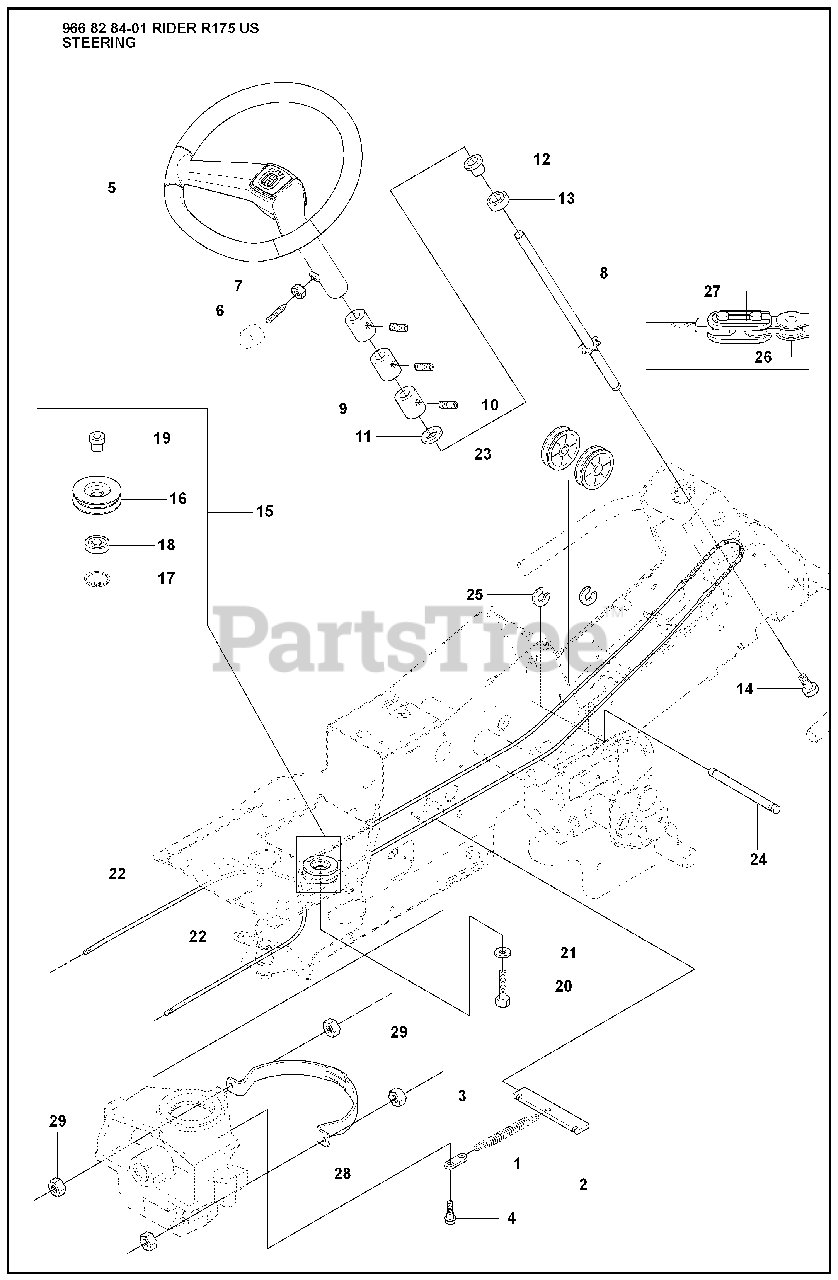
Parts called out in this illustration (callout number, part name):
2	SPRING BRACKET
5	STEERING WHEEL
7	NUT
8	ROD STEERING ASSY
9	SPACER
13	BALL BEARING 6004-2RS1
17	CIRCLIP SGH 47
18	BALL-BEARING 6204-2RS
22	RP STEERING CABLE COMPLETE
25	RETAINING RING
26	STEERING CHAIN
28	WIRE GUIDE
29	NUT
